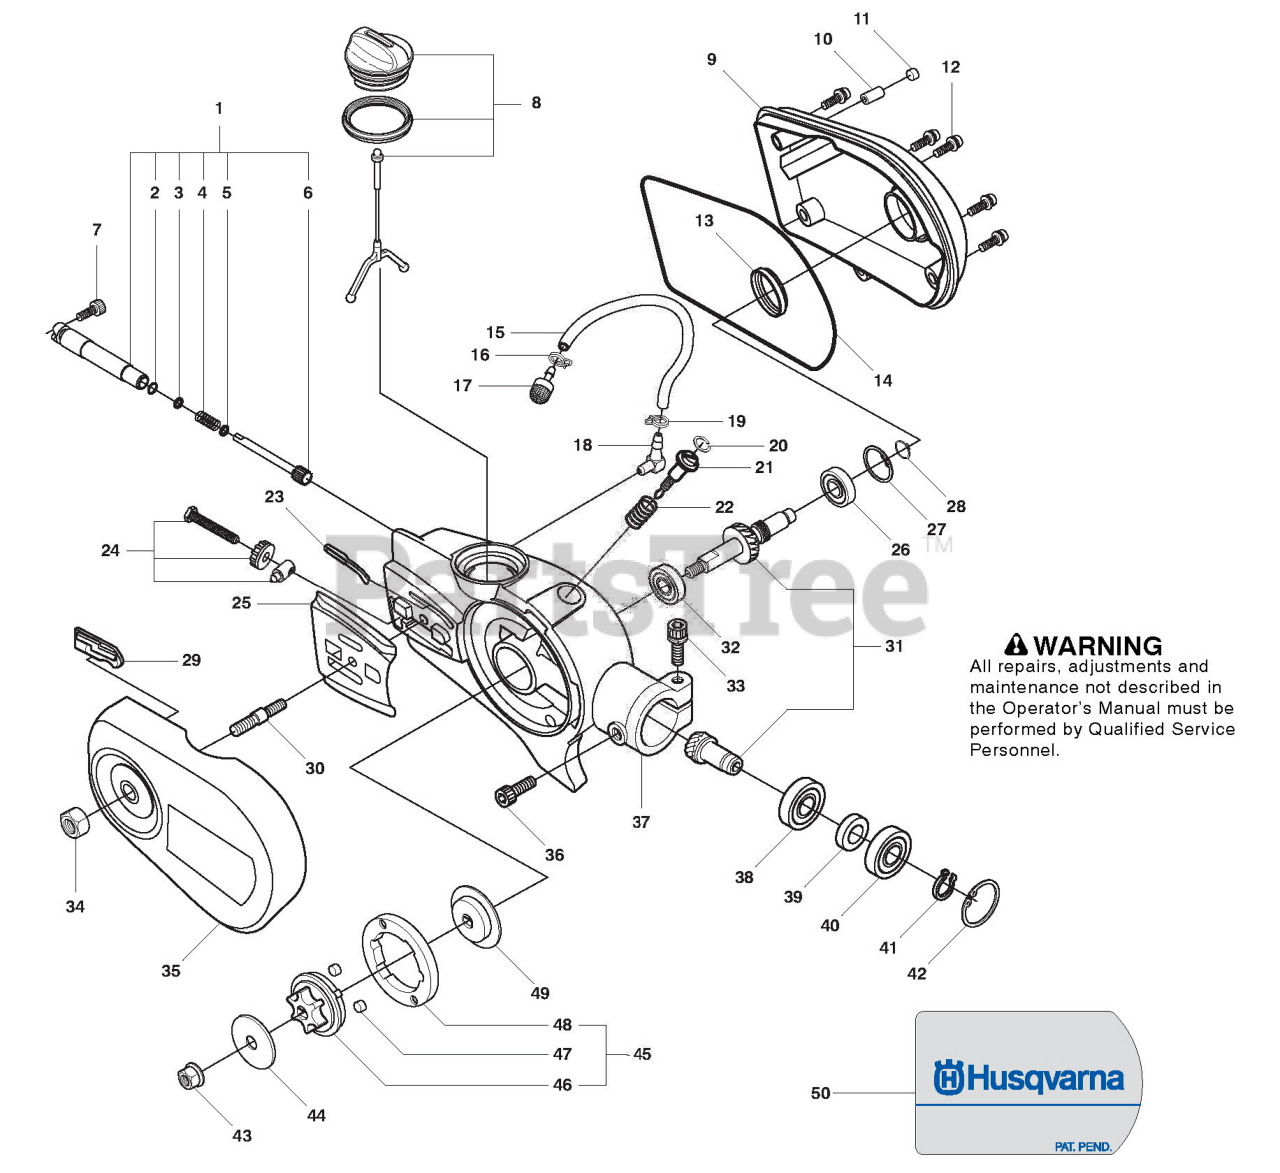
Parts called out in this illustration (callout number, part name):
1	Assy - Oil Pump
3	Washer Steel
5	Washer Steel
6	Pump Piston
8	Assy - Tank Cap
16	Hose Clamp
17	Oil Filter
18	Fitting - Pulse Inlet
19	Hose Clamp
24	Chain Tensioner
25	Chain Guide Plate
26	Ball Bearing
29	Seal - Chain guide
31	Assy. Drive Shaft (gear)
32	Ball Bearing
34	Nut
38	Ball Bearing
40	Ball Bearing
41	Ring - Retainer
42	Ring - Retainer
43	Flange Nut
44	Washer Steel
47	Rubber Bushing
